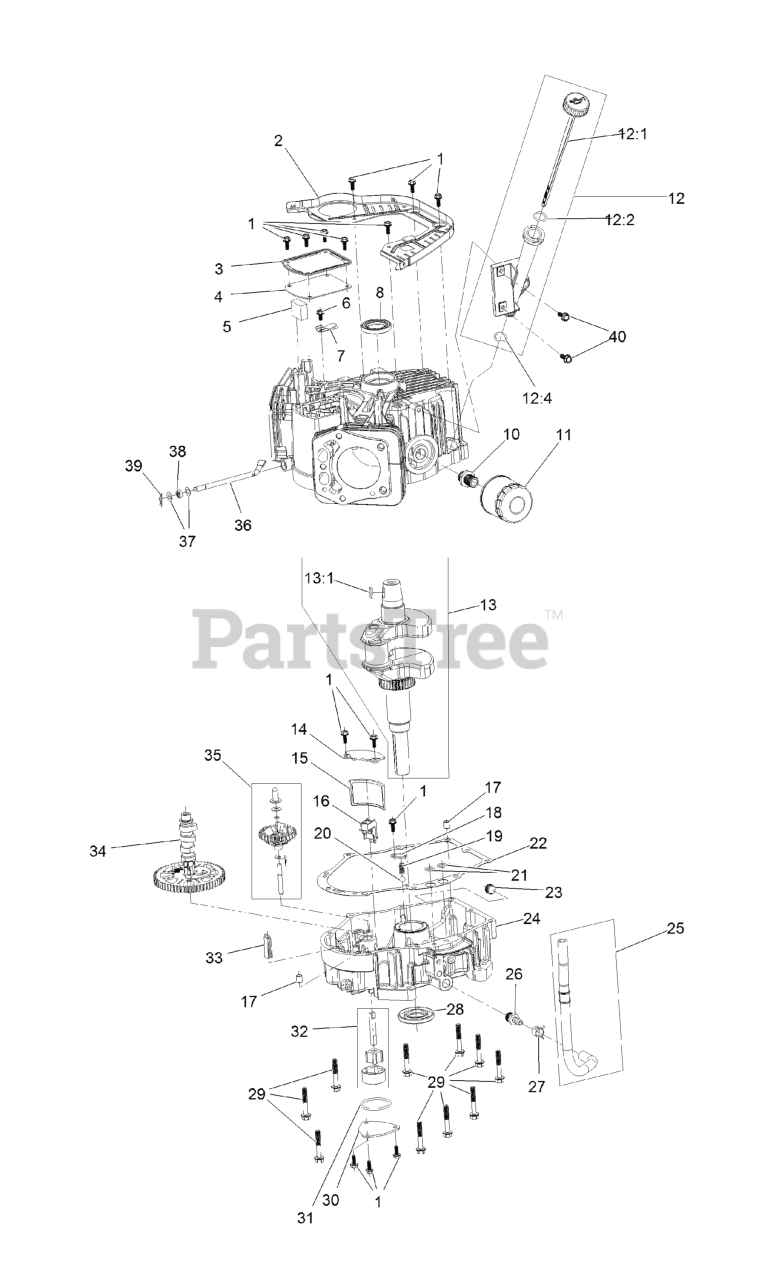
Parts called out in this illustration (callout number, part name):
1	SCREW-HHF
3	COVER-BREATHER
4	GASKET-BREATHER
5	FILTER-BREATHER
6	SCREW-HHF
7	VALVE-BREATHER
8	SEAL-OIL
10	ADAPTOR-FILTER, OIL
11	FILTER-OIL
12	OIL TUBE ASM
12:1	DIPSTICK
13	CRANKSHAFT
13:1	KEY-WOODRUFF
14	COVER-SCREEN, OIL
15	SCREEN-OIL
16	RETAINER-SCREEN
17	PIN-DOWEL
18	PLATE-RETAINER
20	VALVE-BALL
22	GASKET-COVER, CRANKCASE
23	PLUG-DRAIN
24	COVER-CRANKCASE
25	OIL DRAIN HOSE ASM
26	FITTING-HOSE
27	CLAMP-HOSE
29	SCREW-HHF
30	COVER-OIL PUMP
32	OIL PUMP ASM
33	DEFLECTOR-OIL, RUBBER
34	CAMSHAFT
35	GOVERNOR ASM
36	SHAFT-GOVERNOR
37	WASHER-PLAIN
38	SEAL-OIL
39	PIN-HAIR
40	SCREW-HHF
